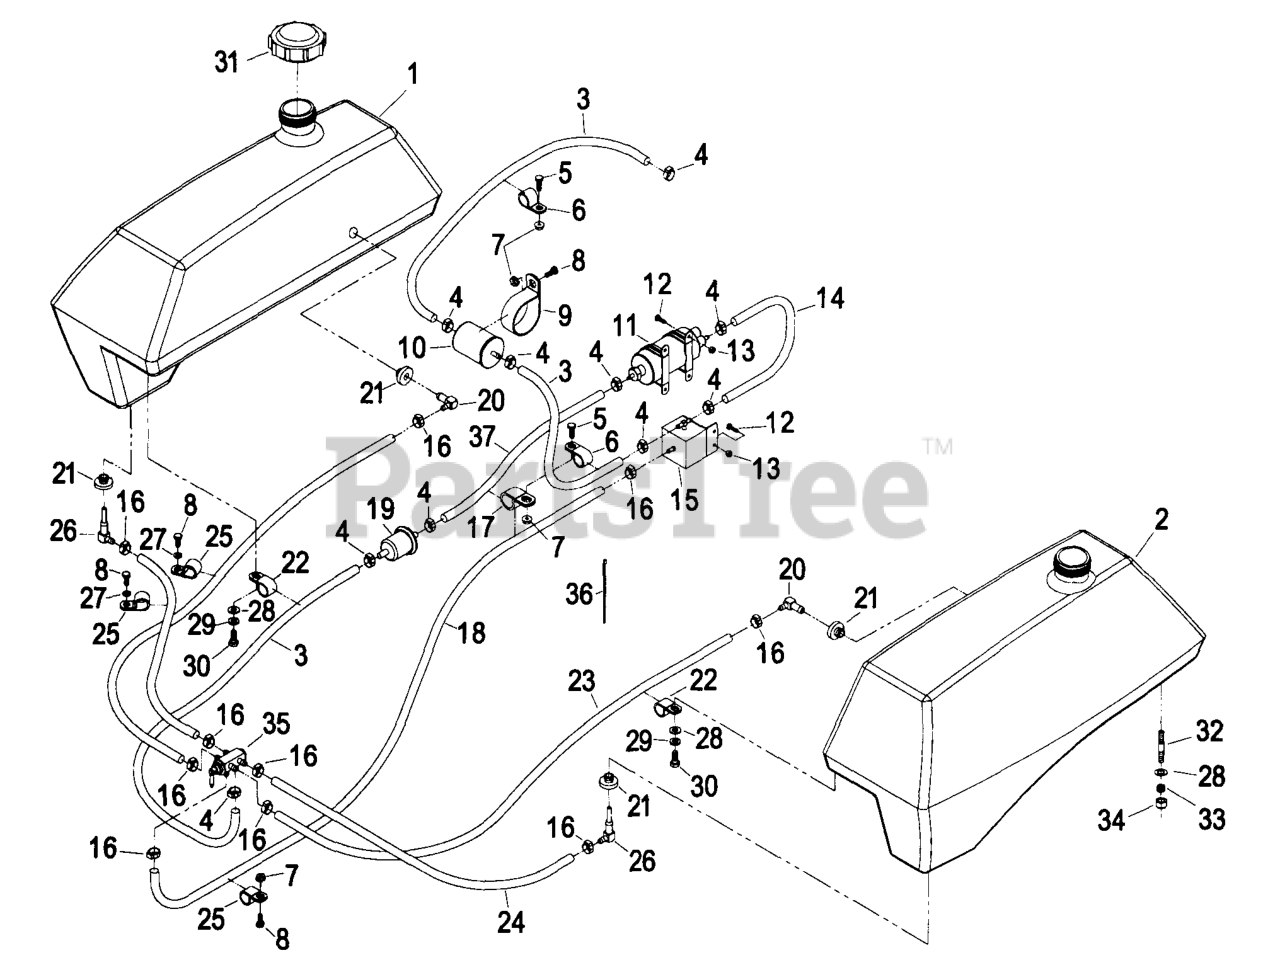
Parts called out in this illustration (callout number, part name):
4	CLAMP-HOSE, FUEL
6	CLIP-LOOM
9	CLIP-LOOM
10	Fuel Filter (Large)
11	Fuel Pump
14	HOSE-FUEL
15	Fuel Regulator
16	CLAMP-HOSE, FUEL
17	CLIP-LOOM
19	Fuel Filter
20	ELBOW-90 DEG
22	CLIP-LOOM
24	HOSE-FUEL
25	CLIP-LOOM
26	ELBOW-TANK, FUEL
27	WASHER-LOCK
29	WASHER-LOCK
31	CAP-FUEL
32	STUD
33	SPRING-TANK, FUEL
35	VALVE-FUEL, DUAL FLOW
36	TIE-CABLE
37	HOSE-FUEL
